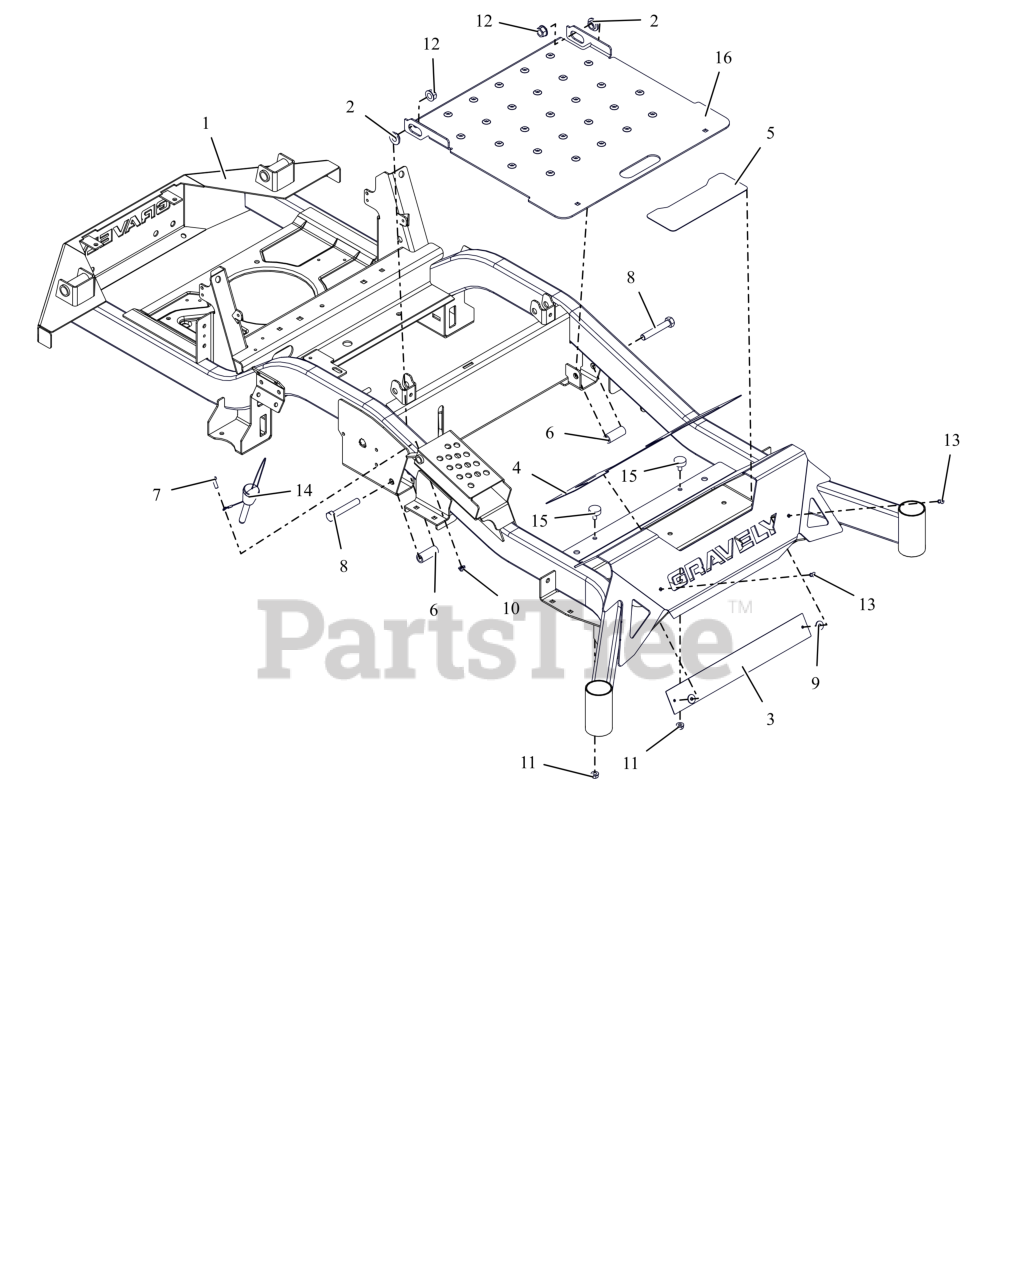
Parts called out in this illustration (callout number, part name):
1	WLDMT, MAIN FRAME -HD 60 (RED)
2	BSHG-FLG .515X.750X.310X1.120
3	PLATE, BACK FOOT-REST XL
4	GRIP, FRONT
5	GRIP, STEP
6	SPACER, .515X.75X1.83
7	BLT, HEX .25-20X.75 G5 ZCC
8	BLT, HEX .50-13X3.00 G5 ZCC
9	WSHR, RBR W/ADHESIVE .25X.75X.06
10	NUT,NYL-FLG .25-20 GF ZCC
11	NUT,SPNLK-FLG .31-18 G5 ZCC
12	NUT-LK-TOP-FLG .500-13 GF ZCC
13	RIVET, #66 STEEL POP PD BLACK
14	PIN, MAGNETIC .50X2.50
15	BUMPER, RUBBER
16	KIT,ACCESS PANEL W/DECALS-RED
